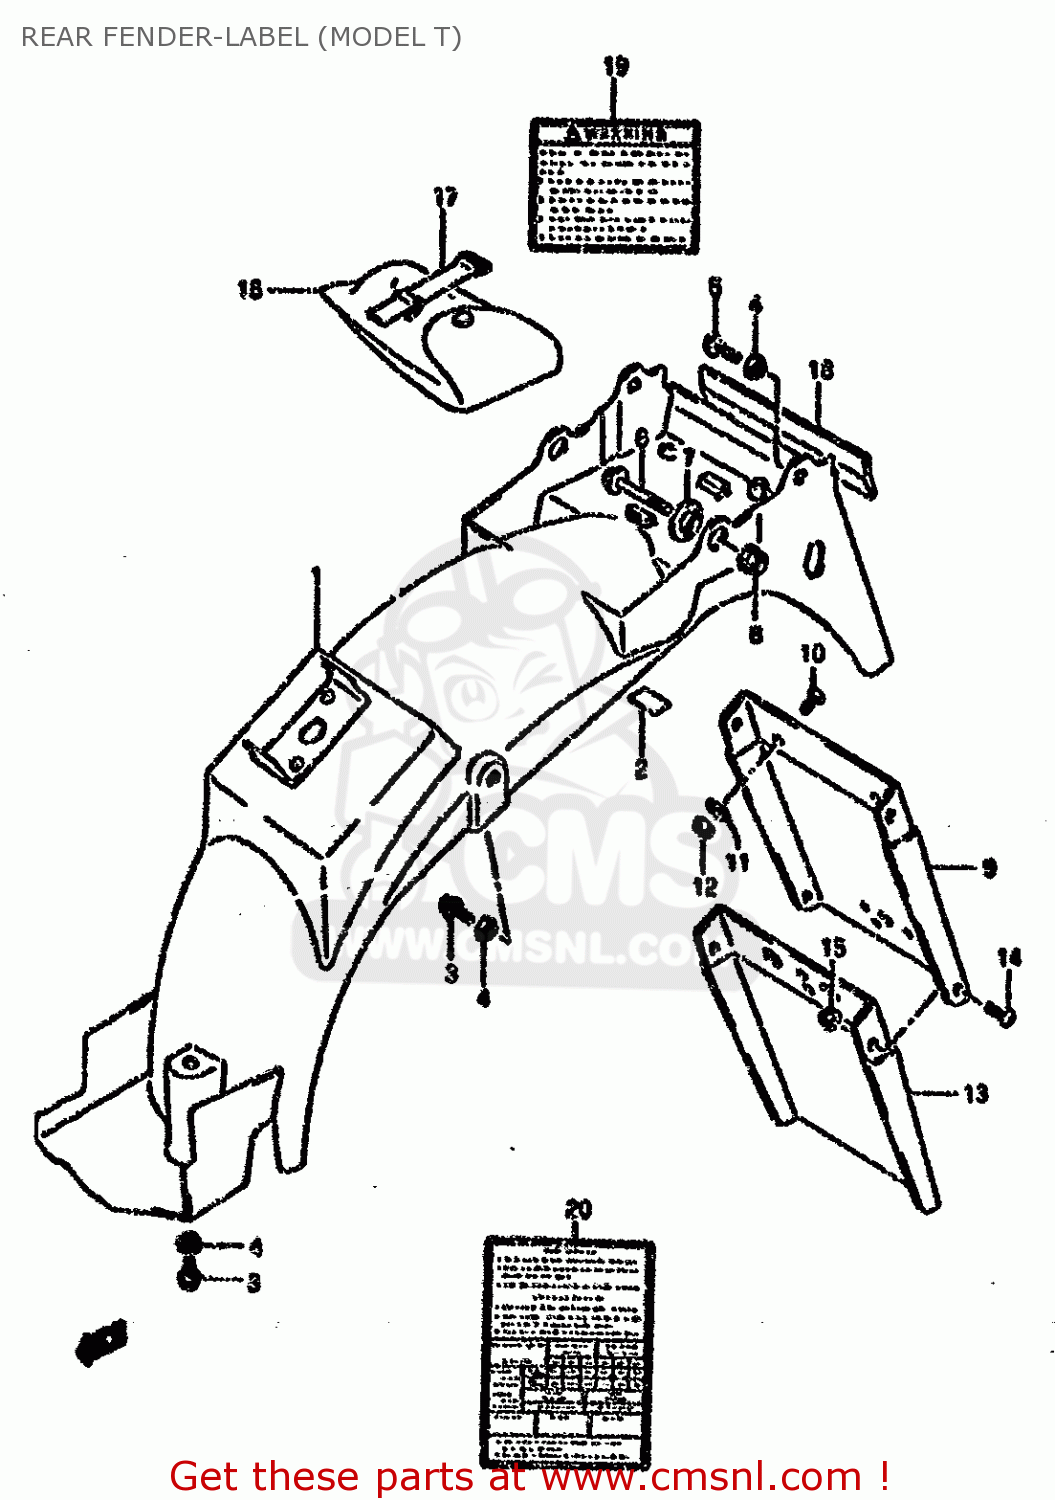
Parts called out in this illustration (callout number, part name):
1	FENDER,RR
2	TAPE,RR FENDER
3	BOLT
4	WASHER
5	BOLT
6	BOLT
7	WASHER
8	NUT
9	EXTENSION,REAR FENDER
10	SCREW
11	WASHER(6.5X16X1.2)
12	NUT
13	MUDGUARD,RR FENDER
14	SCREW
15	NUT
16	TOOL ASSY
17	BAND
18	CUSHION,RR FENDER
19	LABEL, WARNING SAFETY
20	LABEL,TIRE AIR PRESSURE
21	LABEL,CAUTION
22	LABEL,TIRE AIR PRESSURE
23	MANUAL,OWNER'S
